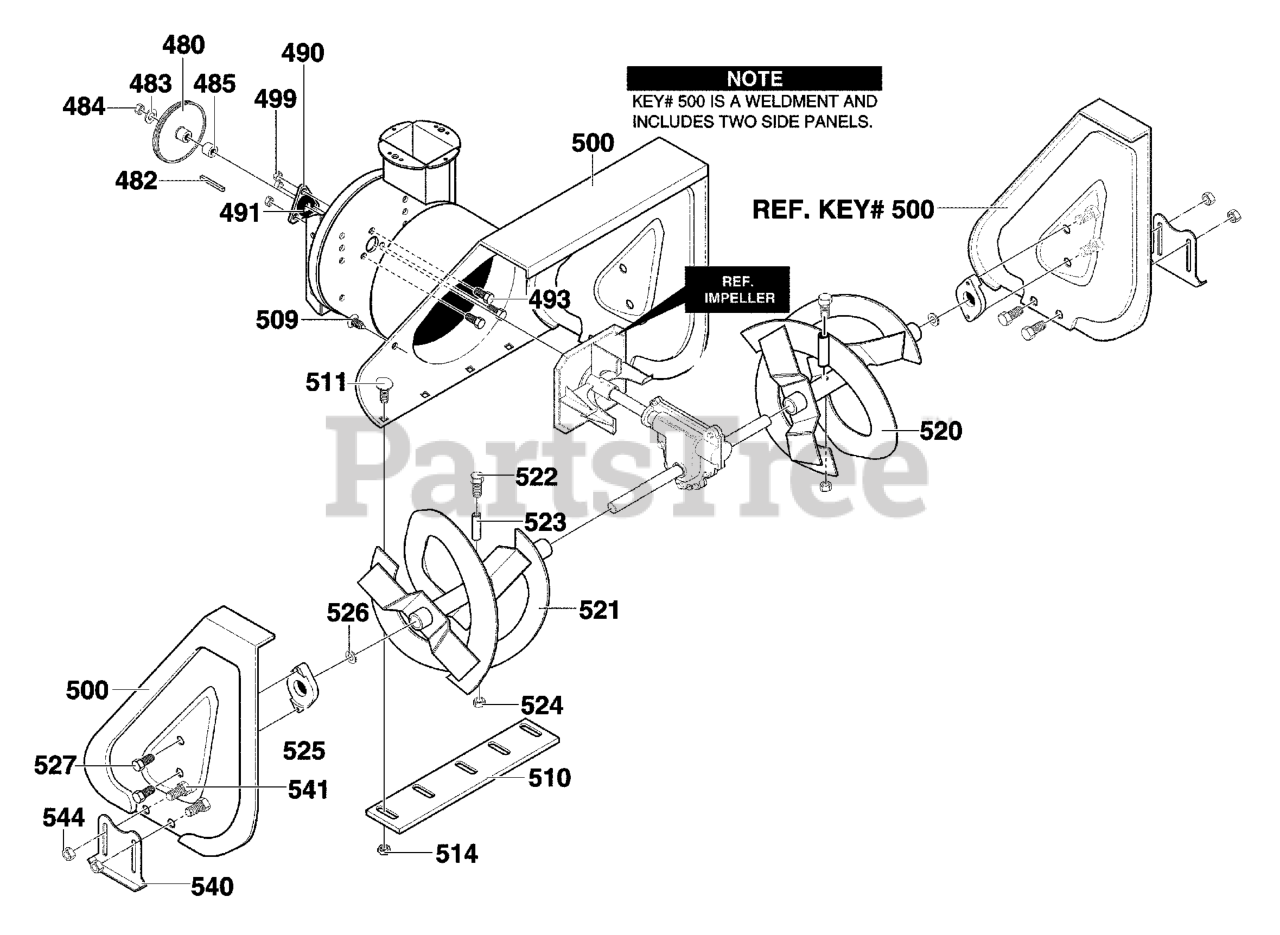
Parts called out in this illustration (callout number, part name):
482	KEY, SQUARE
483	FLATWASHER
484	NUT, 1/4-20
485	SPACER, FRICTION PULLEY
490	RETAINER, BALL BRNG
491	BEARING, BALL
493	BOLT, HEX - 0.31-18X0.50
499	NUT, 5/16-18 HEXWDFLLK
500	HOUSING, ASSY
509	PLUG, CHRISTMAS TREE
510	BLADE, SCRAPER
511	BOLT, 1/4-20X.75
520	AUGER, ASSY, LH
521	AUGER, ASSY, RH
522	SCREW, 1/4-20X1.75
523	SPACER, SLEEVE
524	NUT, 1/4-20
525	BEARING,FLANGE
527	SCREW, 5/16-18 x 0.75
540	SKID, HEIGHT ADJUST
541	BOLT, 5/16-18 X .75
544	NUT, 5/16-18 REGHEX
